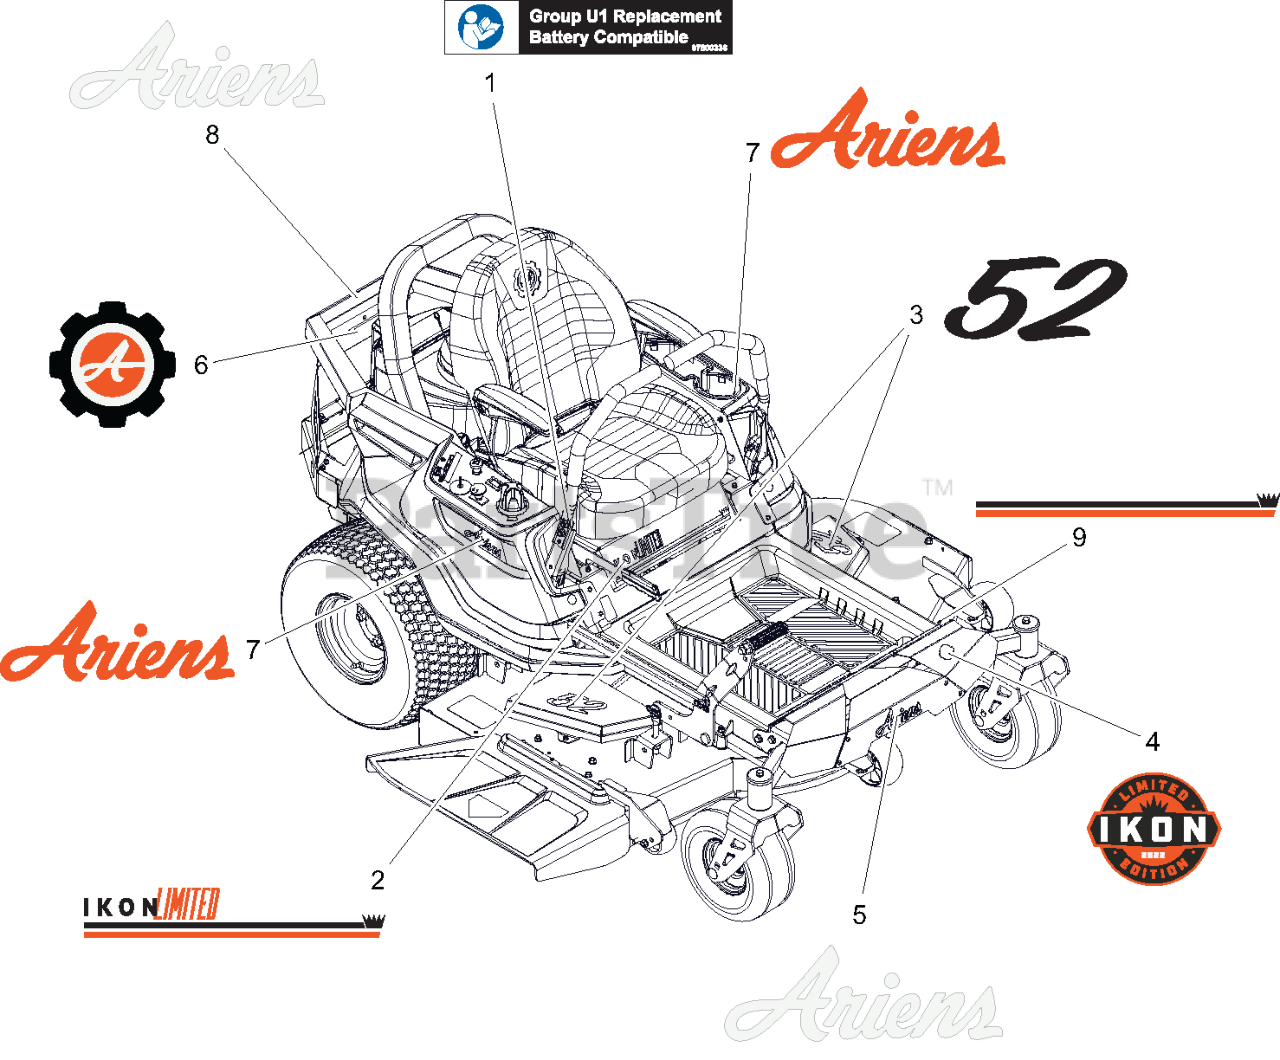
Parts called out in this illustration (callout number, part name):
1	DECAL, U1 BATTERY REPLACEMENT
2	DECAL- IKON XD LIMITED
3	DECAL- 52
4	DECAL- IKON LIMITED EASTER EGG
5	DECAL, LIMITED EDITION ARIENS
6	DECAL- ARIENS HERITAGE GEAR
7	DECAL, ARIENS SCRIPT - ORANGE
8	DECAL, ARIENS SCRIPT - WHITE
9	DECAL, DECK ACCENT
